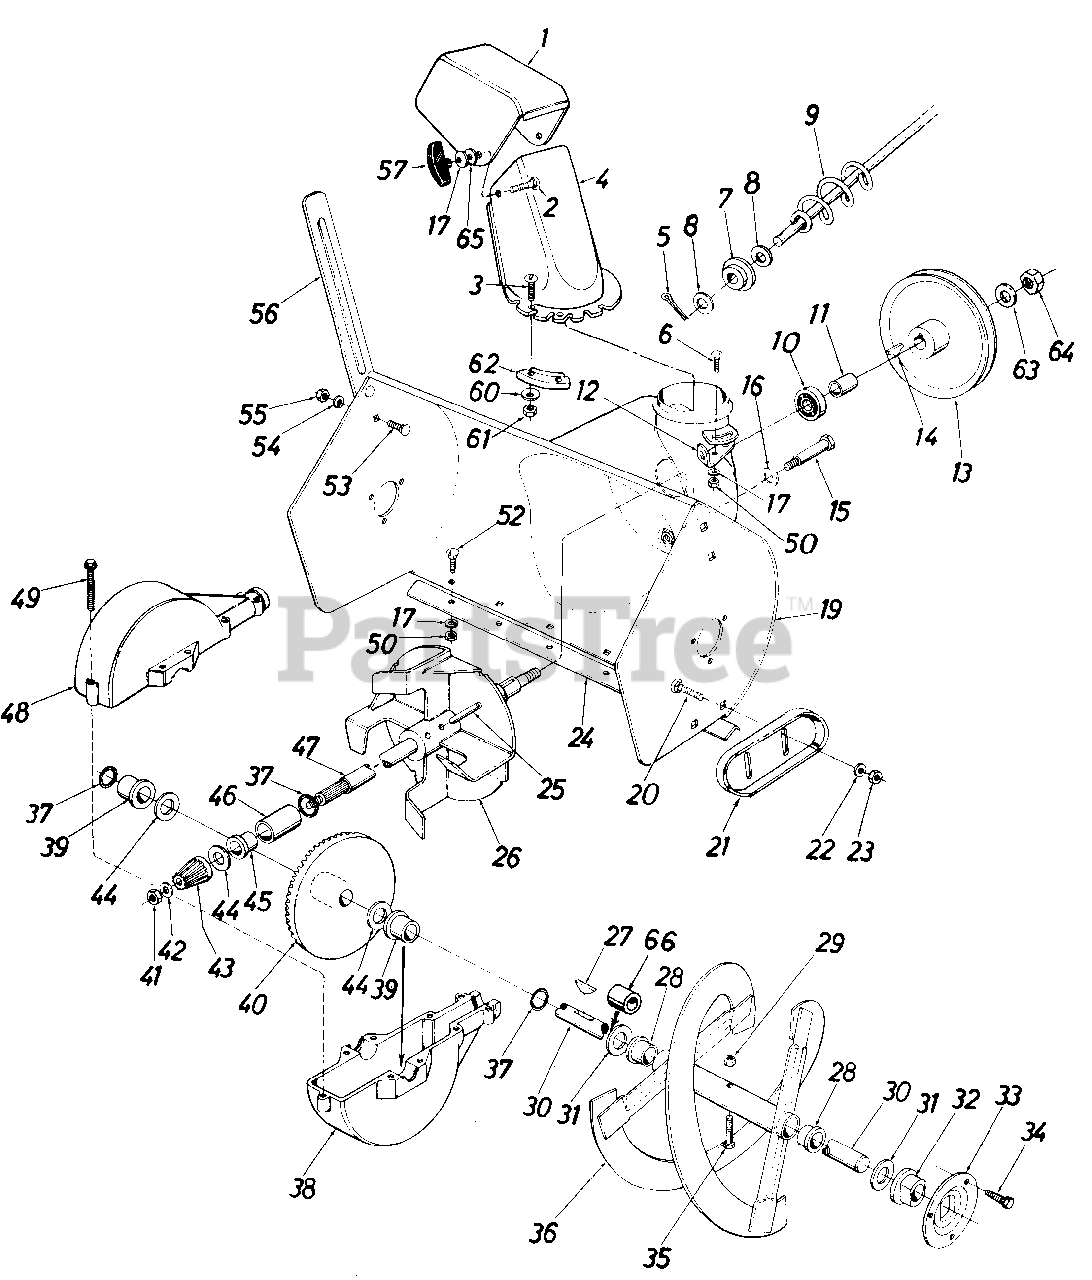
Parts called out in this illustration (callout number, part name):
1	Top Chute Ass'y.
2	Carriage Bolt 5/16-18 x 1.0"
3	Truss Mach. Scr. Bolt 1/4-20 x .75"
4	Chute
5	Cotter Pin
6	Carriage Bolt 5/16-18 x .75"
7	Bushing
8	Fl-Wash. .385 I.D. x .62" O.D.
9	Chute Crank Ass'y.
10	Ball Brg 62" I.D. x 1.38" 0. D .
11	Spacer .63" I.D. x .88" O.D. x .900" Lg.
13	1/2" "V"-Pulley .625" I.D. x 7.50" O.D.
14	#61 Hi-Pro Key 3116" x 518" Dia.
15	Shld. Bolt .50" Dia. x 2.11"
16	Bell-Wash. .40" I.D. x .88" O.D. x .06
17	Bell-Wash. .34" I.D. x .88" O.D.
20	Carriage Bolt 3/8-16 x .62"
21	Slide Shoe
22	Bell-Wash. 3/8" I.D.
23	Hex Jam Nut 3/8-16 Thd.
24	20" Shave Plate
26	11" Dia. Blower Fan Ass'y.
27	#9 Hi-Pro Key 3/16 x 314" Dia.
28	Flange Brg. .75" I.D. x .88" O.D. x .62
29	Hex Ins. L-Nut 5/16-18
30	Spiral Axle
31	Fl-Wash. .75" I.D. x 1.50" O.D. x .06
32	Flange Brg. w/Flats .755"
33	Bearing Housing
34	Hex Wash. Hd. Self-Tap Scr. 5/16-24 x .50" Lg.
35	Hex Bolt 5/16-18 x 1.50" Lg.
36	20" Spiral Ass'y.-L.H.
37	"O"-Ring-3/4" I.D.
38	Bevel Gear Housing-Lower Half
39	Plastic Flange Brg. .755" I.D.
40	Bevel Gear
41	Hex Cent. L-Nut 5/16-24 Thd.
42	Fl-Wash. .34" I.D. x .62" O.D. x .06
43	Pinion Gear
44	Fl-Wash. .75" I.D. x 1.25" O.D. x .06
45	Flange Brg. .755" I.D.
46	Sleeve Brg. .755" I.D.
47	Blower Axle
48	Bevel Gear Housing- Upper Half
49	Hex Wash. Hd. Self-Tap Scr. 1/4-20 x 1.00" Lg.
50	Hex Nut 5/16-18 Thd.*
52	Carriage Bolt 5/16-18 x .62" Lg.*
53	Carriage Bolt 5/16-18 x .62" Lg.*
54	L-Wash. 5/16" I.D.
55	Hex Nut 5/16-18 Thd.
56	Drift Cutter Bar
57	Knob
60	Fl-Wash. 1/4" I.D.
61	Hex L-Nut 1/4-20 Thd.
62	Chute Flange Keeper
63	Fl-Wash. .64" I.D. x .94 O.D. x .06
64	Hex Jam Nut 5/8-18 Thd.,
65	Fl-Wash. .344 I.D. x 1.125 O.D.
66	Spacer
